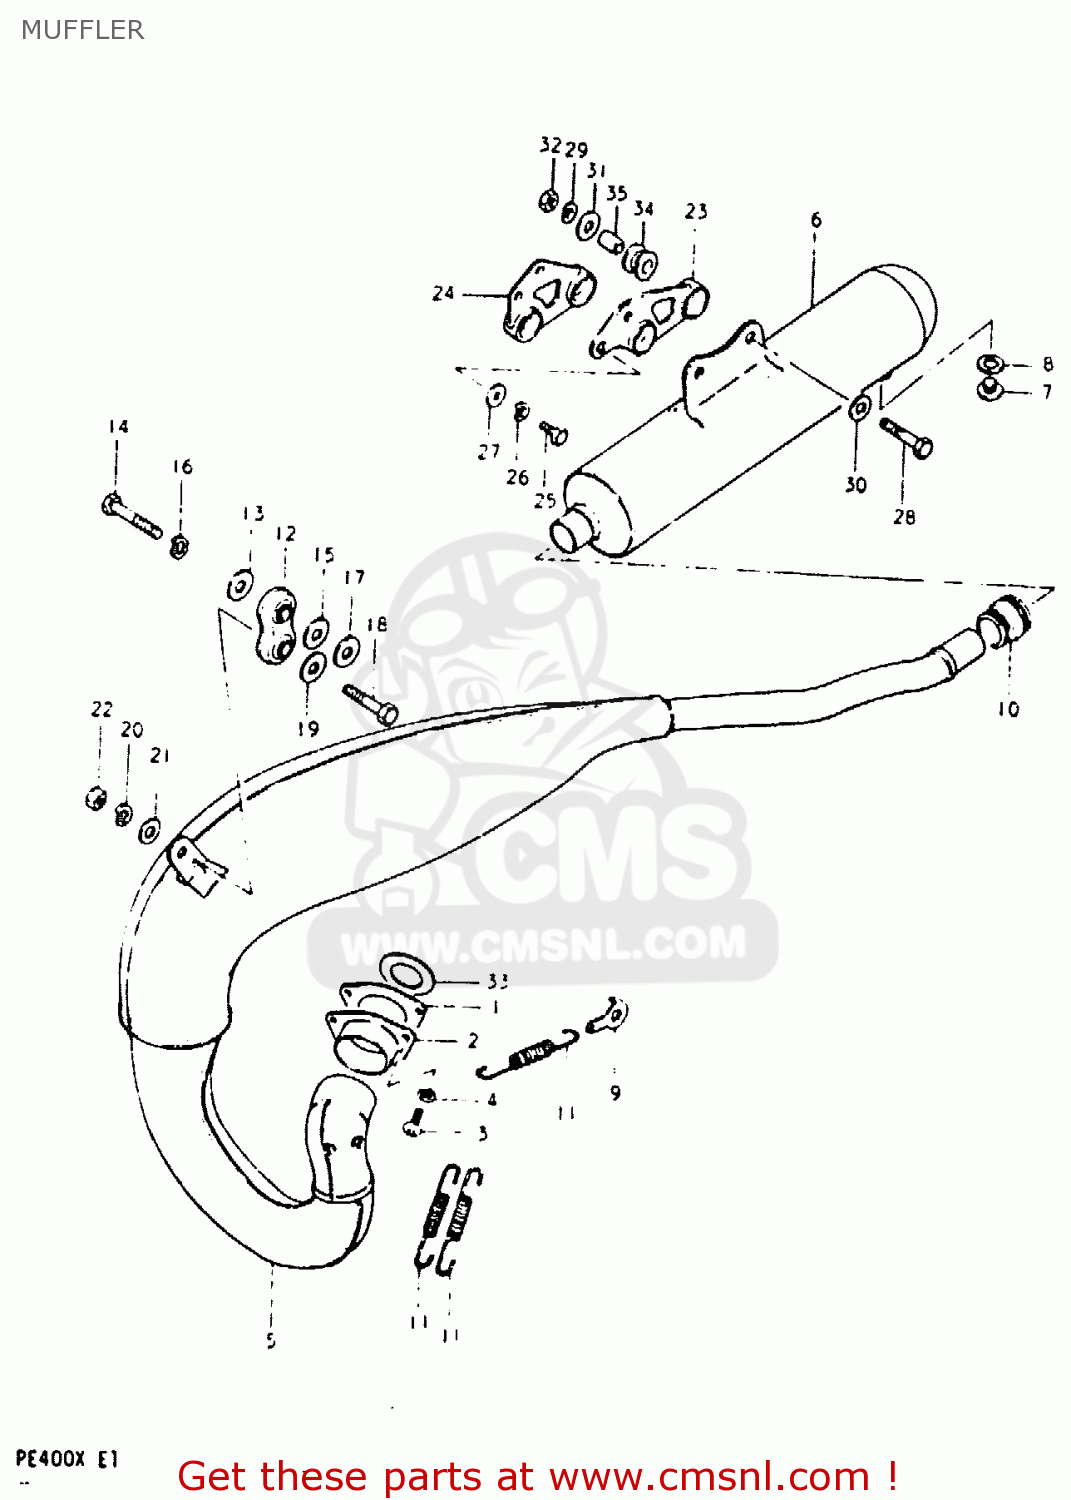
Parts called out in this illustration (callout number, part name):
1	GASKET,EXHAUST PIPE (MCA)
2	FLANGE,EXHAUST PIPE
3	SCREW
4	LOCK WASHER
5	BODY,MUFFLER
6	MUFFLER, 2ND
7	PLUG(12X9)
8	GASKET(12X16X2) (NAS)
9	HOOK,MUFFLER FIT SPRING
10	CONNECTOR,MUFFLER
11	SPRING
12	DAMPER,MUFFLER
13	WASHER
14	BOLT 8X45
15	WASHER
16	LOCK WASHER
17	SPACER(8.4X12X12)
18	BOLT
19	WASHER
20	LOCK WASHER
21	WASHER
22	NUT
23	DAMPER,MUFFLER SUPPORT
24	DAMPER,MUFFLER SUPPORT
25	BOLT
26	LOCK WASHER
27	WASHER
28	BOLT
29	LOCK WASHER
30	WASHER
31	WASHER (8.5X29X1.6)
32	NUT
33	PLATE, EXHAUST PIPE
34	CUSHION
35	SPACER (8.2X12X17)
